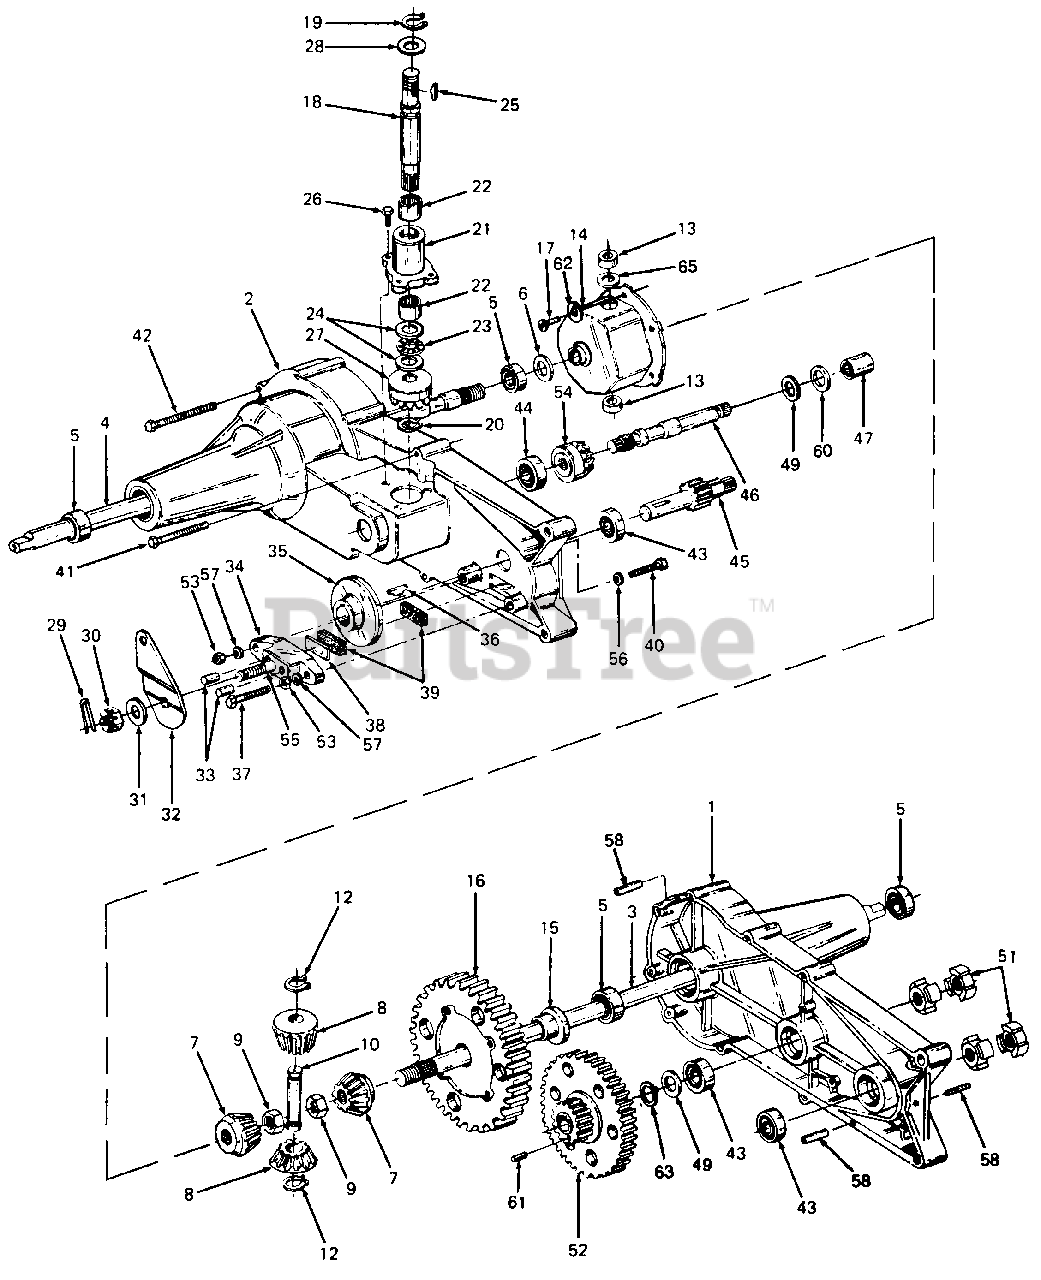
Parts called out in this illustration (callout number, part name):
1	Housing Half, L.H.
2	Housing Half, R.H.
3	Axle, L.H.
4	Axle, R.H.
5	Bearing, Ball
6	Washer, Flat, .76" x 1-1/8" x .306" Thk. Hdn.
7	Gear Miter
8	Gear Miter
9	Nut, Hex Jam Patch Lock, 1/2-20
10	Shaft, Cross
12	Ring, Snap
13	Bearing, Thrust
14	Housing Ass'y. Differential
15	Bearing, Flange, .75" I.D. x 587"
16	Gear, Differential, 72 Tooth
17	Torx Hd. AB-Tap Scr. 1/4 X .62" Lg.
18	Shaft, Input
19	Ring, Snap
20	Ring, Retaining, Ext. 7/16" Dia.
21	Bearing, Input Housing
22	Bearing, Needle, 5/8" I.D. x .50" Lg.
23	Bearing Thrust
24	Washer Flat, 5/8" I.D. x 1.12" O.D. x 030" Thk.
25	Key #4 Hi-Pro, 3/32" x 5/8" Dia. (Hdn.)
26	Screw, Hex Patch Lock, 1/4-20 x 3/4" Lg
27	Gear, Input Pinion, 17 Tooth
28	Washer, Flat, .62" I.D. x 1.0" O.D. x 030" Thk.
29	Pin, Cotter
30	Nut, Castle, 5/16-24 Thd.
31	Washer, Flat, .343" x .88" x .062" Thk.
32	Arm, Brake Actuator
33	Pin, Actuating, 5/16" Dia.
34	Yoke, Brake
35	Disc, Brake
36	Key, Hi-Pro, 3/16" x 5/8" Dia.
37	Screw, Hex Patch Lock, 1/4-20 x 1.5" Lg.
38	Plate, Puck
39	Puck, Brake
40	Screw, Hex Cap, 1/4-20 x 1.5" Lg.
41	Screw, Hex Self-Tap, 1/4-20 x 2.0" Lg
42	Screw, Hex Self-Tap, 1/4-20 x 2.75" Lg
43	Bearing, Ball
44	Bearing, Ball
45	Shaft, Pinion w/11 Tooth Gear
46	Shaft, Drive
47	Bearing, Needle
49	Washer, Flat, 5/8" x 1.12" x 060" Thk.
51	Coupling
52	Gear, Tooth 60 & 17
53	Nut, Hex Jam, 1/4-20 Thd.
54	Gear, Drive Pinion, 17 Tooth
55	Bolt, Square Hd. 5/16-24 Thd.
56	Washer, Flat, .265" x 938" x 12" Thk.
57	Washer, Lock, 1/4" I.D.
58	Pin, Roll, 3/16 Dia. x 50" Lg.
60	Bronze Thrust Brg. 5/8" I.D.
61	Dowel Pin 3/32" x 1/4"
62	Washer, Spring Lock 1/4" I.D.
63	Seal, Grease
65	Washer, Flat, .62" I.D. x 1.0" O.D. x 020" Thk.
